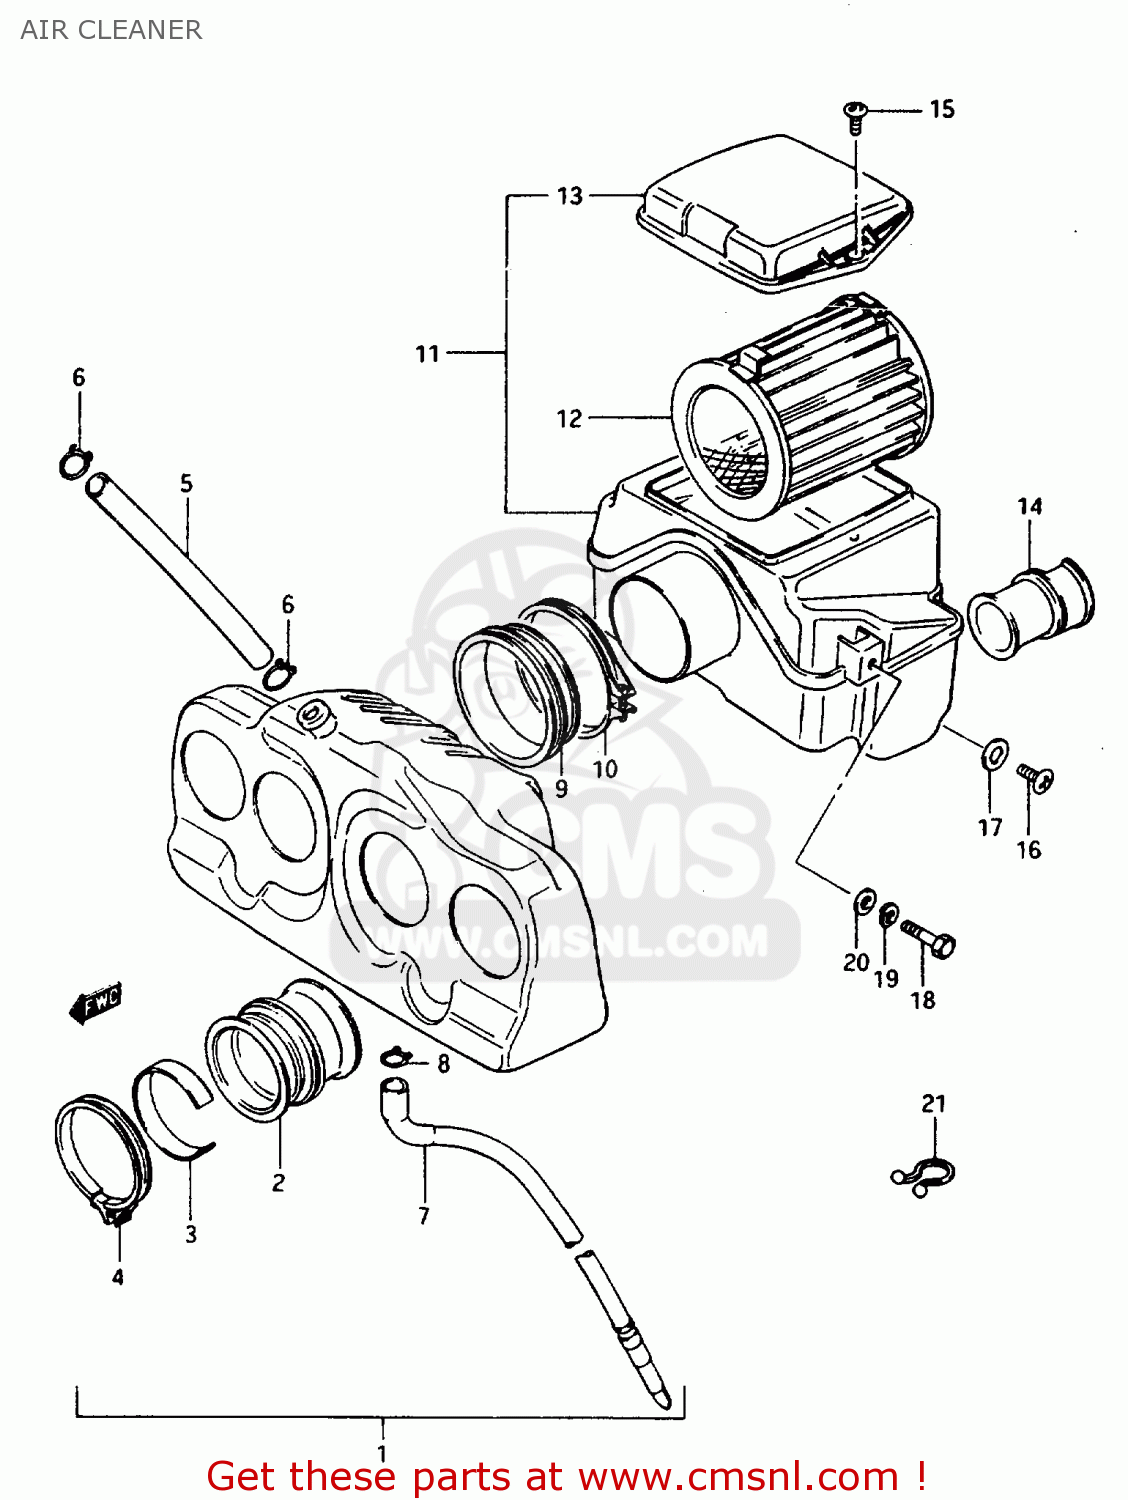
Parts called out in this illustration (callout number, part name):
1	CHAMBER ASSEMBLY,AIR CLEANER
2	TUBE,AIR CLEANER OUTLET
3	RING,CARBURETOR AIR INLET HOSE
4	CLAMP
5	HOSE,BREATHER
6	CLIP
7	DRAIN TUBE
8	CLIP
9	TUBE,JOINT
10	CLAMP
11	CASE ASSEMBLY,AIR CLEANER
12	FILTER,AIR CLEANER
13	CAP,AIR CLEANER
14	TUBE,INLET
15	SCREW M5X12 DIN 7985/N
16	SCREW
17	WASHER
18	BOLT, UPPER
19	LOCK WASHER
20	WASHER
21	CLIP
